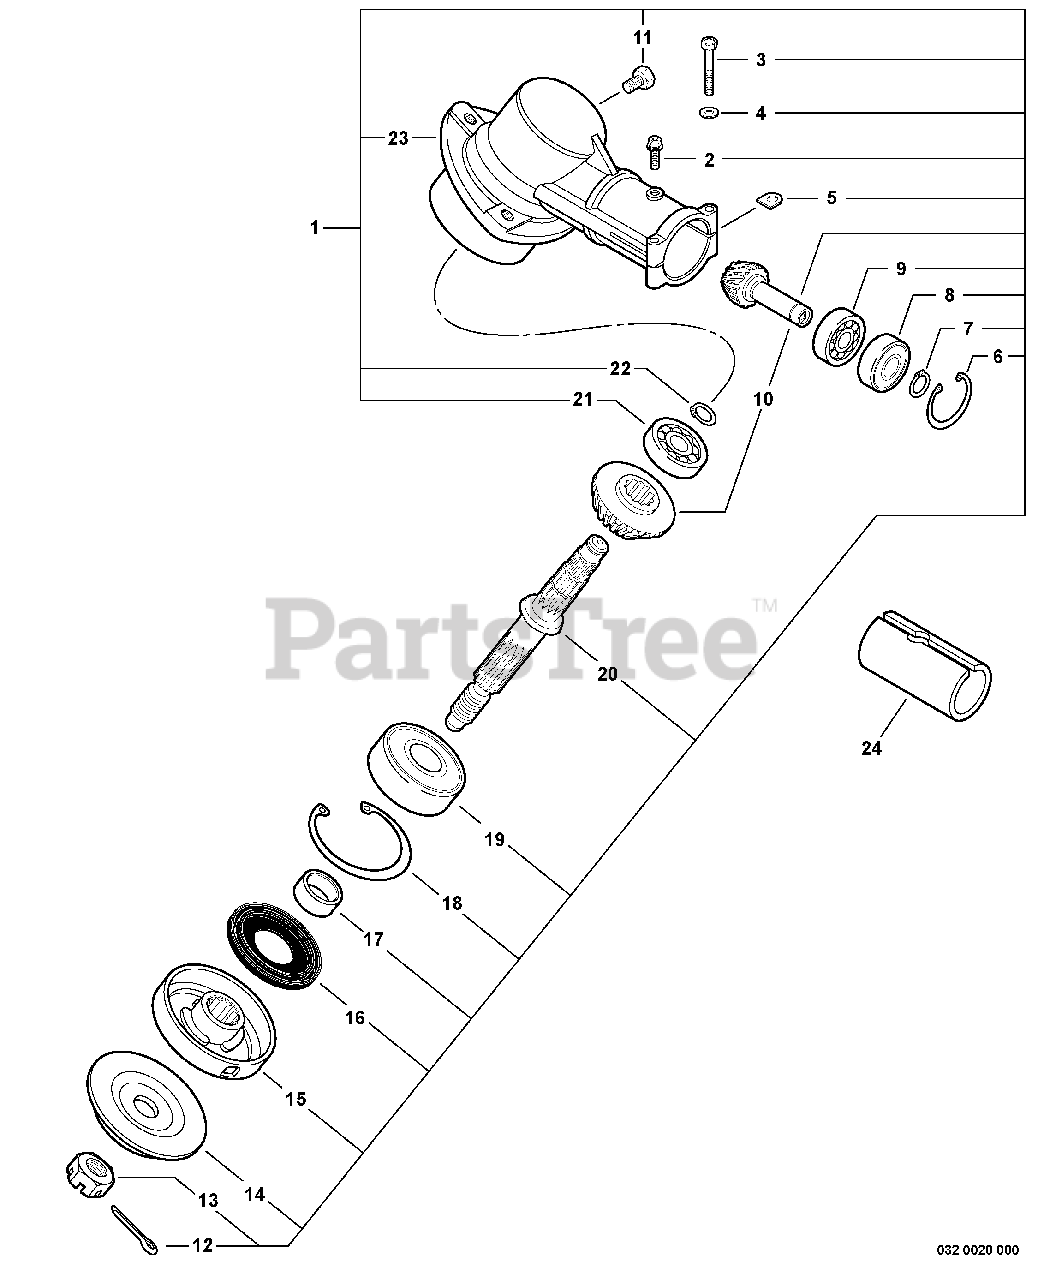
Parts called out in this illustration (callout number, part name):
1	GEAR CASE ASSY
2	SCREW 5×14
3	BOLT 5×30
4	WASHER, FLAT 5.5×10×0.8
6	RING, SNAP 28
7	RING, SNAP Ø12
8	BEARING, BALL 6001
9	BEARING, BALL 6001
10	GEAR SET
11	BOLT M8×8
12	PIN, COTTER 2×22
13	NUT 10×1.25 LH
14	PLATE, ADAPTOR - LOWER
15	PLATE, ADAPTER - UPPER
16	SEAL, OIL 22
17	SPACER 11.8×15×9
18	RING, SNAP Ø32
19	BEARING, BALL - 6201 C3
20	SHAFT, GEAR
21	BEARING, BALL 6000
22	RING, RETAINING - 12
23	CASE, GEAR
